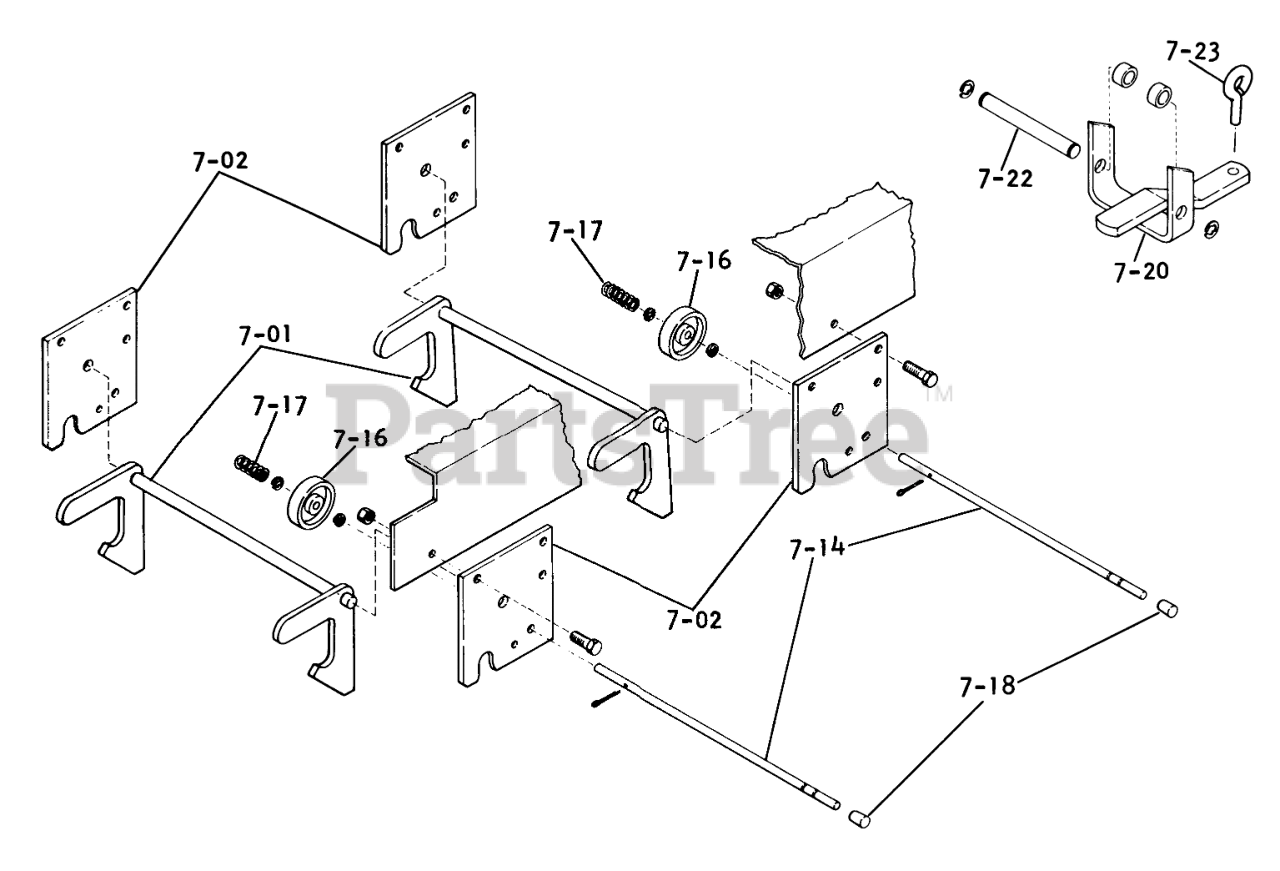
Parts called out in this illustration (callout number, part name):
7-01	Assy-Latch
7-02	Hitch Plate
7-14	Rod Lock
7-17	SPRING-COMPRESSION
7-18	Cap
7-20	Hitch
7-22	Pin
7-23	Pin-Tool
